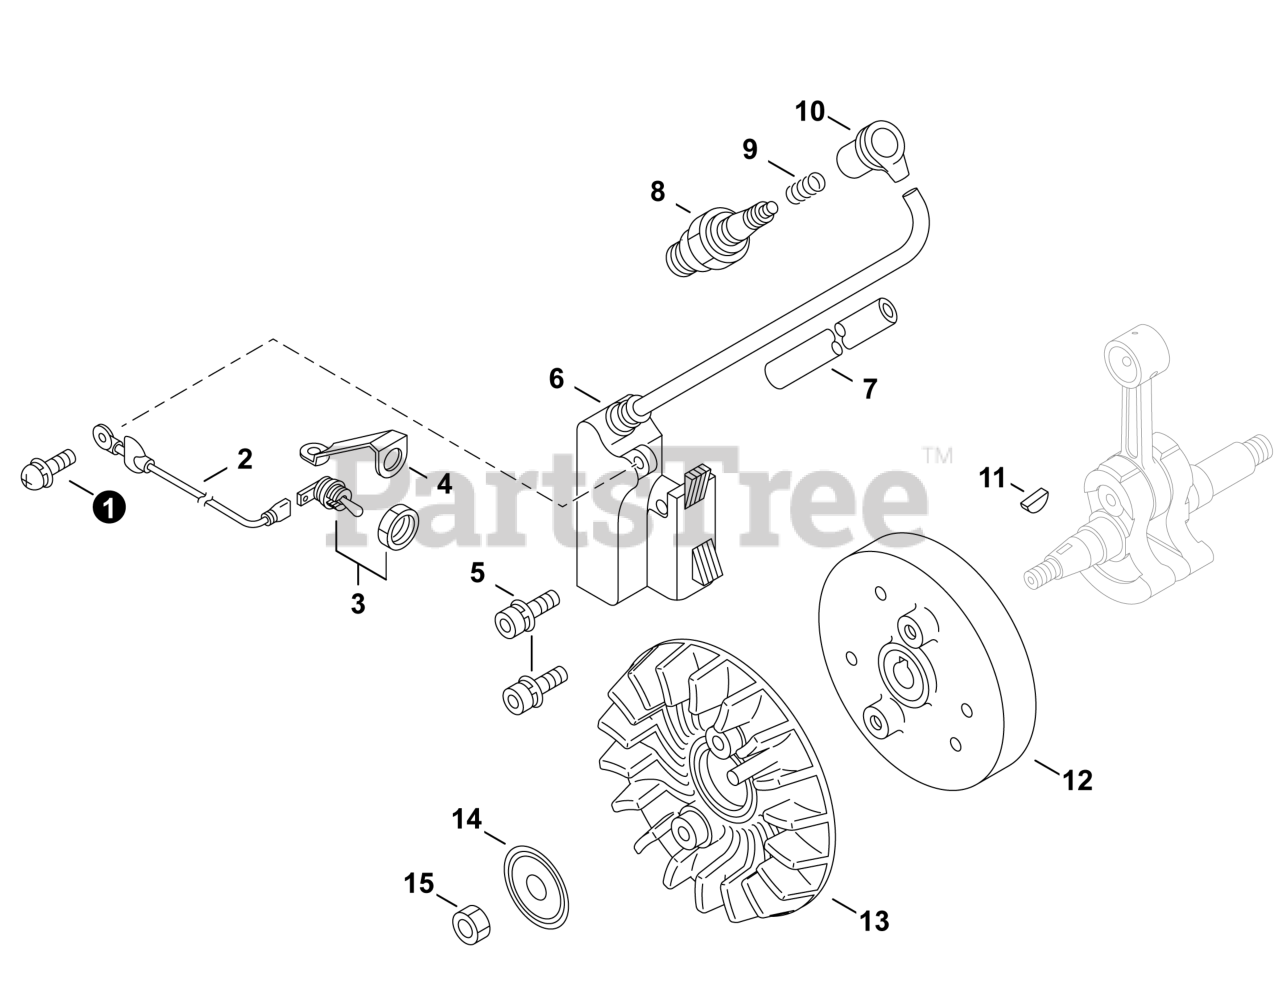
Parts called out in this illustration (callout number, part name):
1	SCREW 4×8
3	SWITCH, ON-OFF
4	PLATE, GROUND
5	BOLT 4×20
6	COIL, IGNITION
8	SPARK PLUG - BPMR7A
9	TERMINAL, SPARK PLUG
10	CAP, SPARK PLUG
11	KEY, WOODRUFF
12	FLYWHEEL
14	WASHER 8.2×31×0.8
